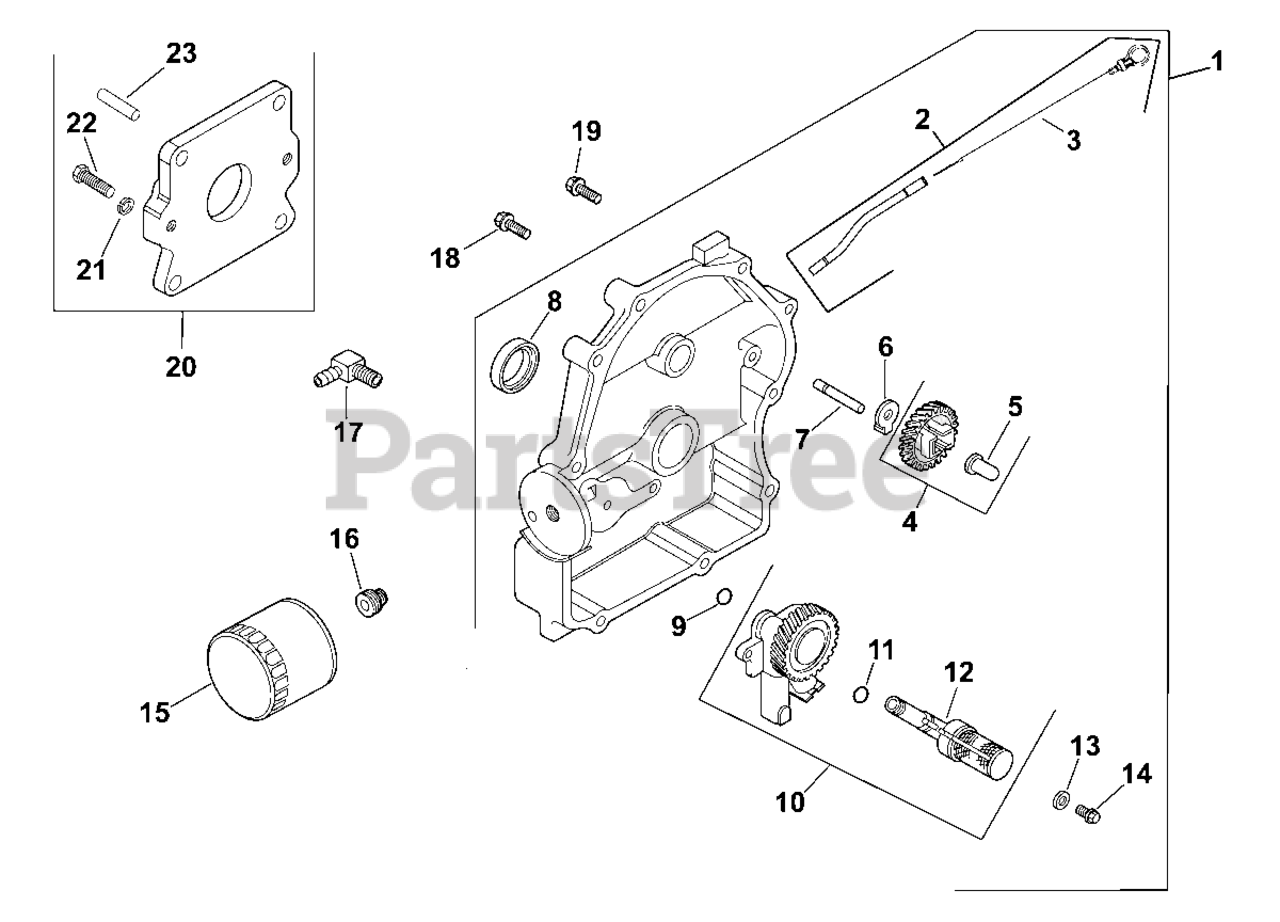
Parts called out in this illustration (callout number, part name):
2	KIT, DIPSTICK/DIPSTICK TUBES
4	KIT, GOVERNOR GEAR W/PIN
5	PIN, GOVERNOR REGULATING
7	SHAFT, GOVERNOR GEAR
8	SEAL, OIL (KM)-USE 25 032 06-S
10	OIL PUMP ASSY KIT-USE 24 393 53-S
11	O-RING, OIL PICK-UP
12	PICK-UP, OIL
13	WASHER, FLAT 6 MM
14	SCREW,FLG THD FRM M6X1.0X25-(#25086395S)
15	OIL FILTER
16	NIPPLE, OIL FILTER USE 24 136 09-S
17	CONNECTOR, 90 DEG. HOSE
18	SCREW, HEX FLANGE -USE 24 086 17-S
19	SCREW, FLG M8X1.25X45
20	KIT, PUMP ADAPTER
21	WASHER, SPRING LOCK 7/16"
22	SCREW,CAP HD 7/16-14x1 1/2"
23	PIN, ALIGNMENT
